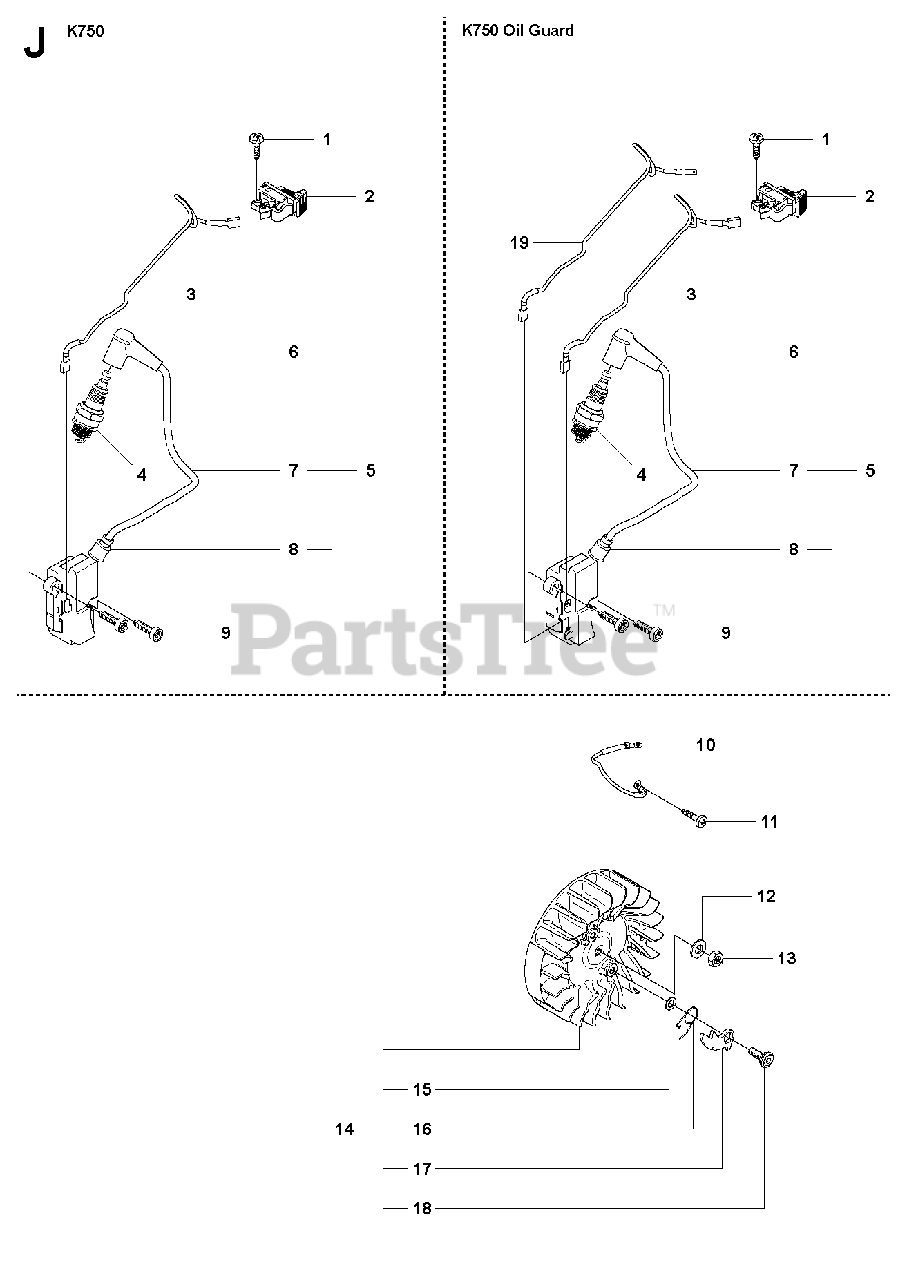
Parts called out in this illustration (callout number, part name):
1	SCREW CCRPANT
2	STOP SWITCH
3	CABLE
3	CABLEOil Guard
5	IGNITION MODULEIncl. 6 - 8
6	SPARK PLUG CAP
7	IGNITION CABLE
9	SCREW ITXSCM
11	SCREW CCRPANT
14	FLYWHEELIncl. 15 - 18
19	CABLEOil Guard
